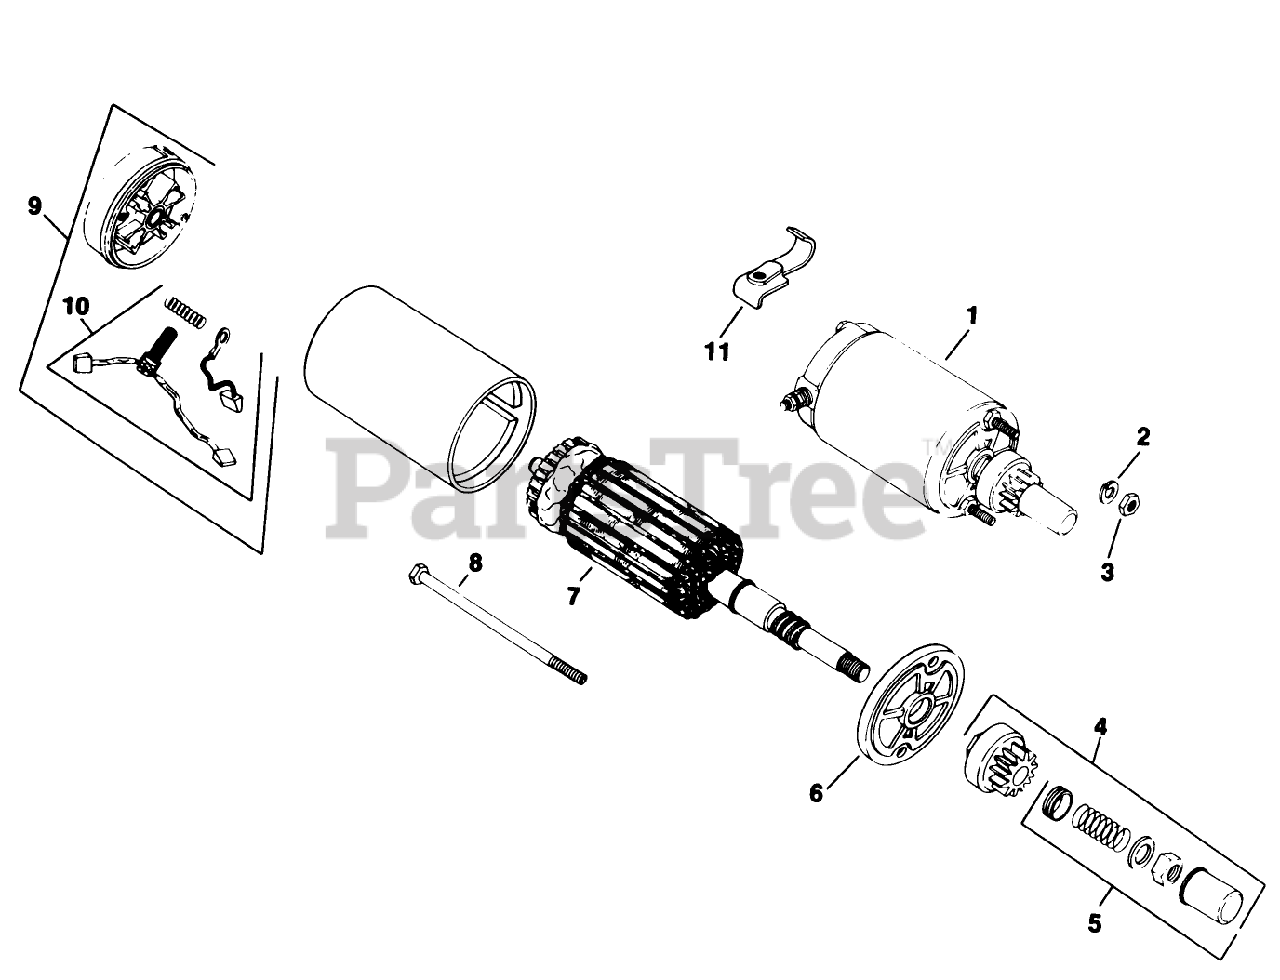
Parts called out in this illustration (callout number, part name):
1	Starter Assy. (Incl. Ref. #4-10)
2	Washer
4	Kit-Drive (Incl. Ref. #5)
5	Kit-Drive Parts
6	Cap-Drive End
7	Armature
9	Cap-Commutator End (Incl. Ref. #10)
10	Kit-Brush
11	Bracket-Mounting
